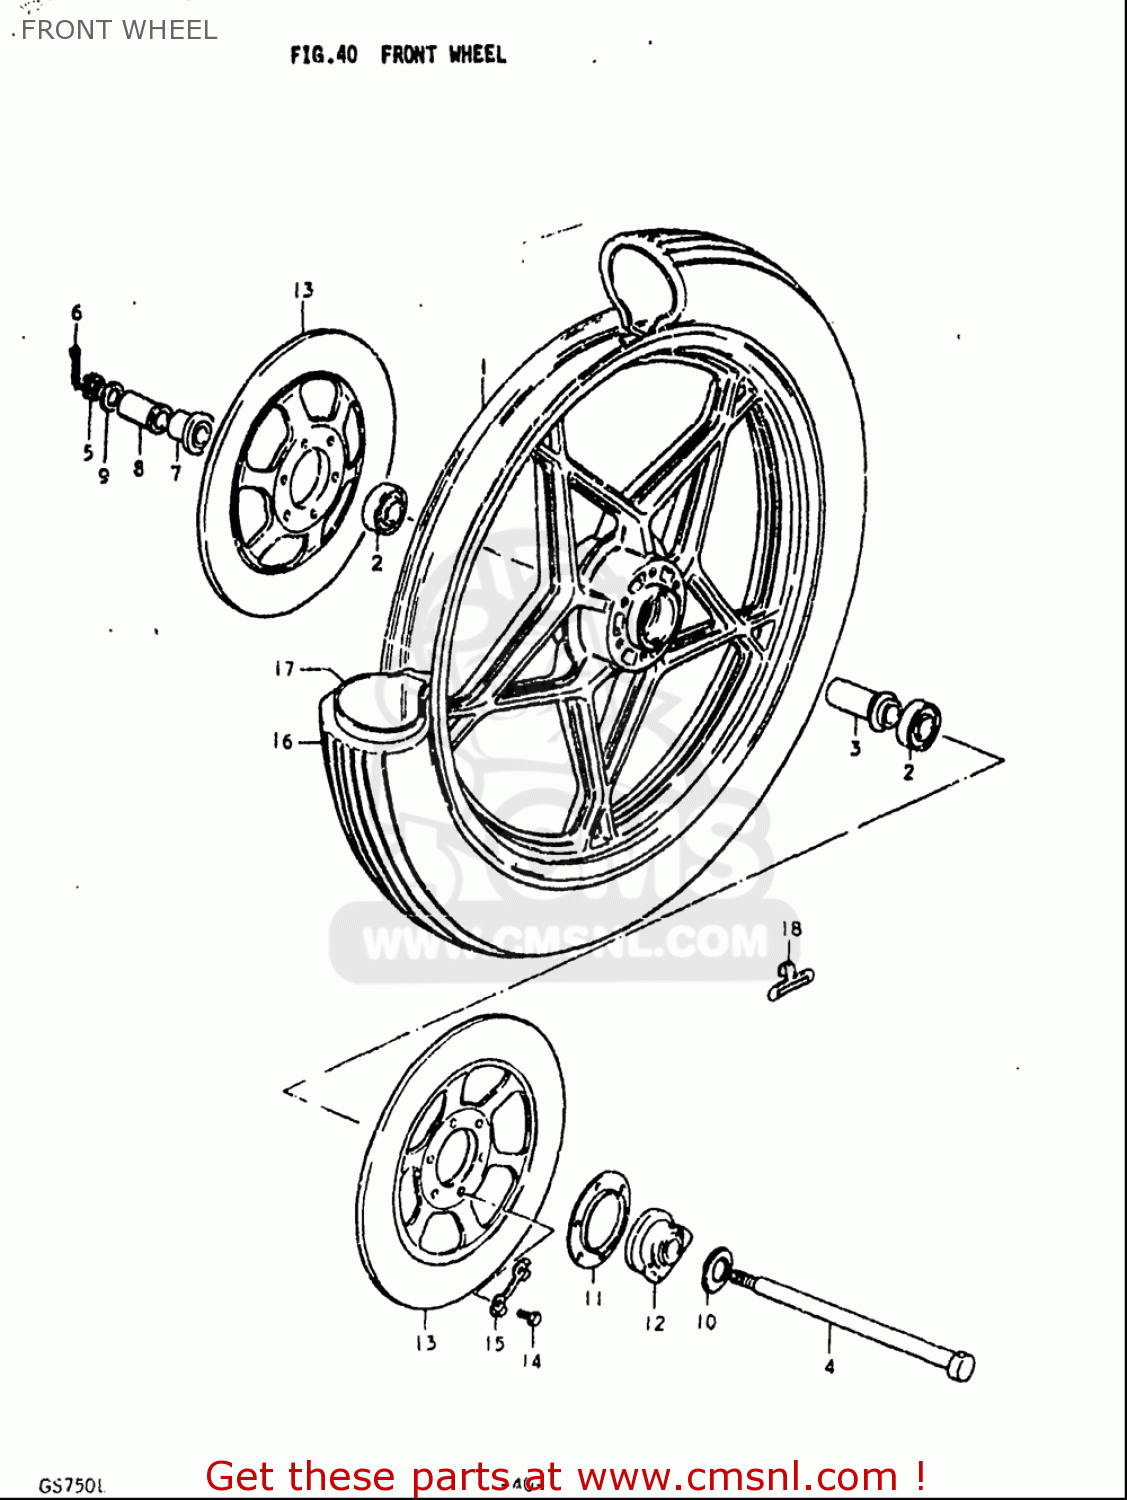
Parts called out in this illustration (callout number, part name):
1	WHEEL,FR(19XMT1.85)
2	B1 15X42X13 BEA
3	SPACER,FR HUB BEARING
4	AXLE,FR
5	NUT 12MM
6	PIN
7	SPACER,FR AXLE,R
8	SPACER
9	WASHER
10	WASHER(15.5X26X2.3)
11	DUST SEAL,SPEEDOMETER GEAR BOX
12	BOX ASSY,SPEEDOMETER GEAR
14	BOLT(8X25)
15	WASHER
17	TUBE ASSEMBLY,WHEEL,INNER
18	BALANCER,WHEEL
